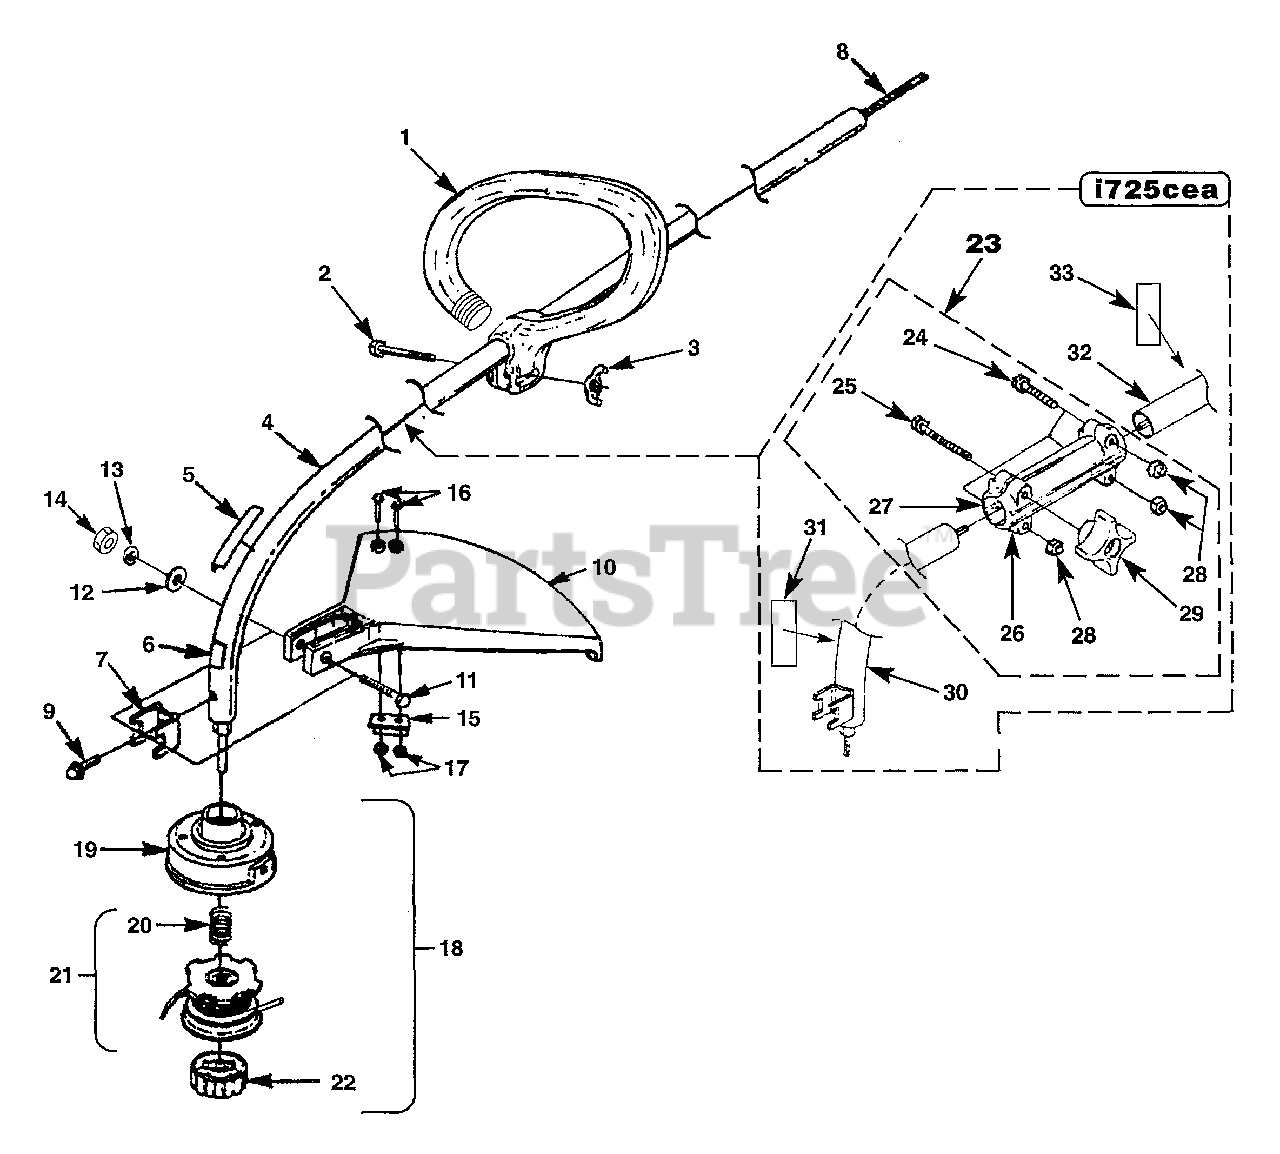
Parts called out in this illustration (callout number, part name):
1	FRONT HANDLE ("D")
2	SCREW-Cap Hex Hd. (10-24 X 2")
3	NUT-Wing (10-24)
4	HOUSING-Drive Shaft
5	DECAL-Starting Inst.
6	DECAL-Warning
7	CLAMP
8	SHAFT-Flexible
9	SCREW
10	DEFLECTOR & BLADE KIT (100 Degree)
11	SCREW-Cap Hex Hd. (1/4-20 X 2")
12	WASHER-Flat (1/4")
13	WASHER-Lock (1/4")
14	NUT-Hex (1/4-20)
15	BLADE-Cut-Off Kit
16	SCREW-Mech. Hex Hd. (10-24 X 7/8")
17	NUT-Hex (10-24)
18	STRINGHEAD-Complete (.080" Line)
19	HOUSING & EYELET (Dual Line)
20	SPRING-Compression
21	SPOOL & STRING (.080" Line)
22	RETAINER-Spool (R.H. Thread, Black)
23	COUPLER ASSEMBLY
24	BOLT-Hex Hd.
25	SCREW-Cap Hex (1/4-20 x 2")
26	SPLIT BOOM (L.H.)
27	SPLIT BOOM (R.H.)
28	NUT-Hex (1/4-20)
29	KNOB
30	DRIVE SHAFT HOUSING-Curved (Lower)
31	DECAL-Warning
32	DRIVE SHAFT HOUSING- (Upper)
33	DECAL-Start Instructions
